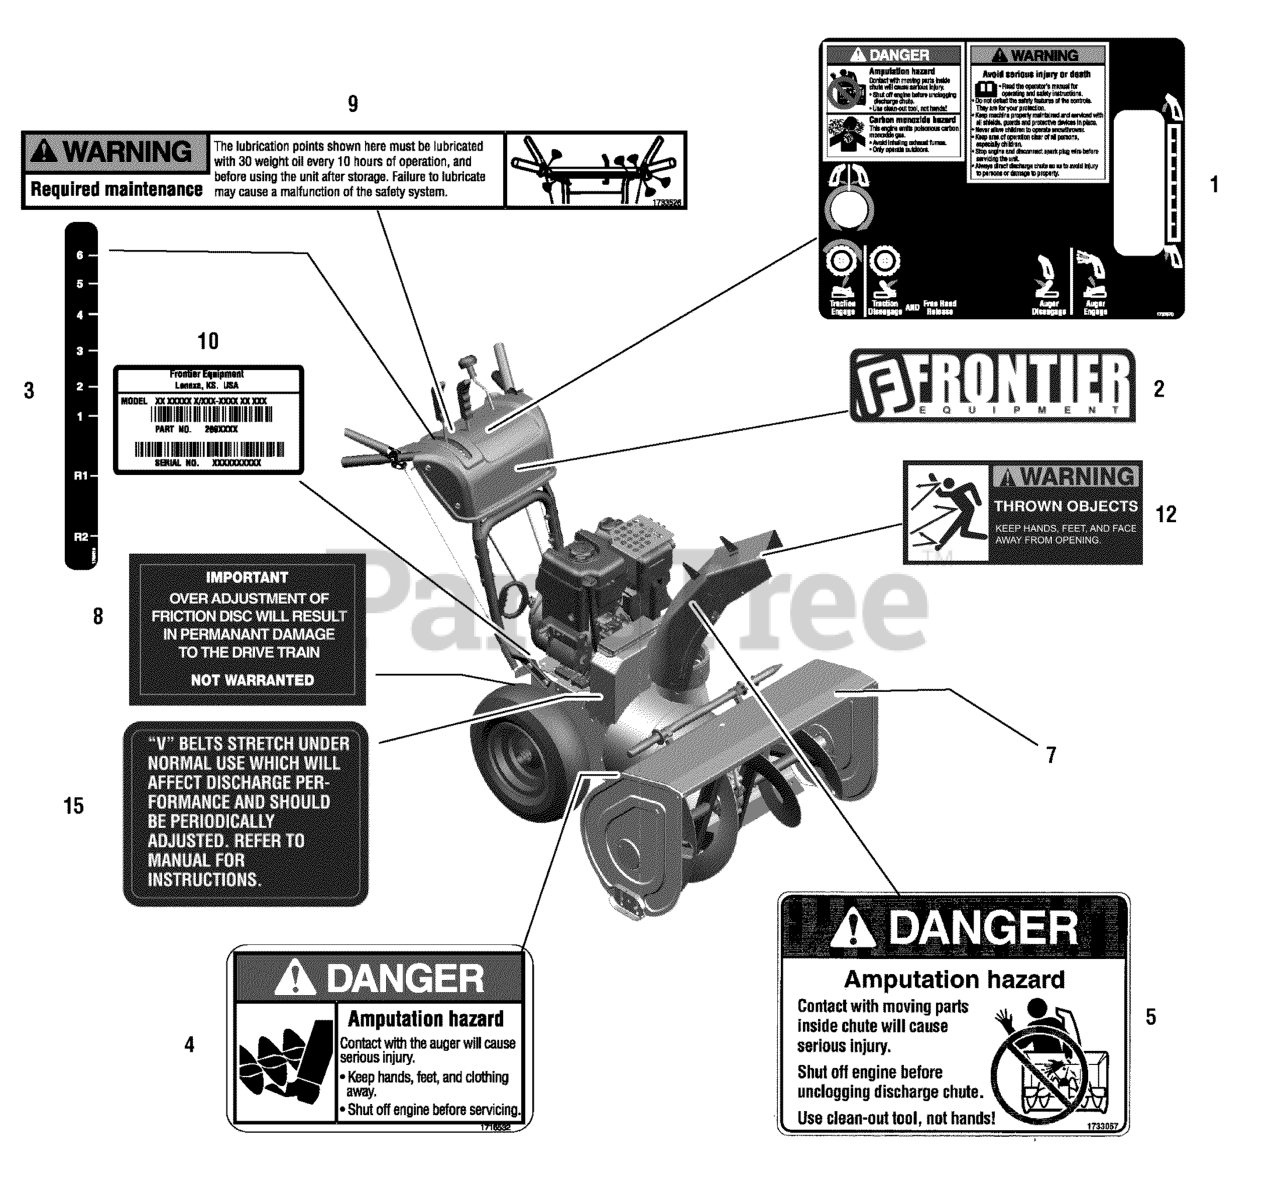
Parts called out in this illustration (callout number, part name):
1	DECAL, Dashboard
2	PLATE, John Deere
3	DECAL, Shift
4	DECAL, Danger Avoid Injury from Auger
5	DECAL, Danger Amputation Hazard
6	DECAL, OPEI Certified ANSI *
7	DECAL, ST8528
7	DECAL, ST9530S
7	DECAL, ST1332S
8	DECAL, Over Adjustment of Friction Disc
9	DECAL, Lubrication
10	STICKER, Serial with Bar Code
12	DECAL, Thrown Objects
15	DECAL, V-Belt Adjustment
